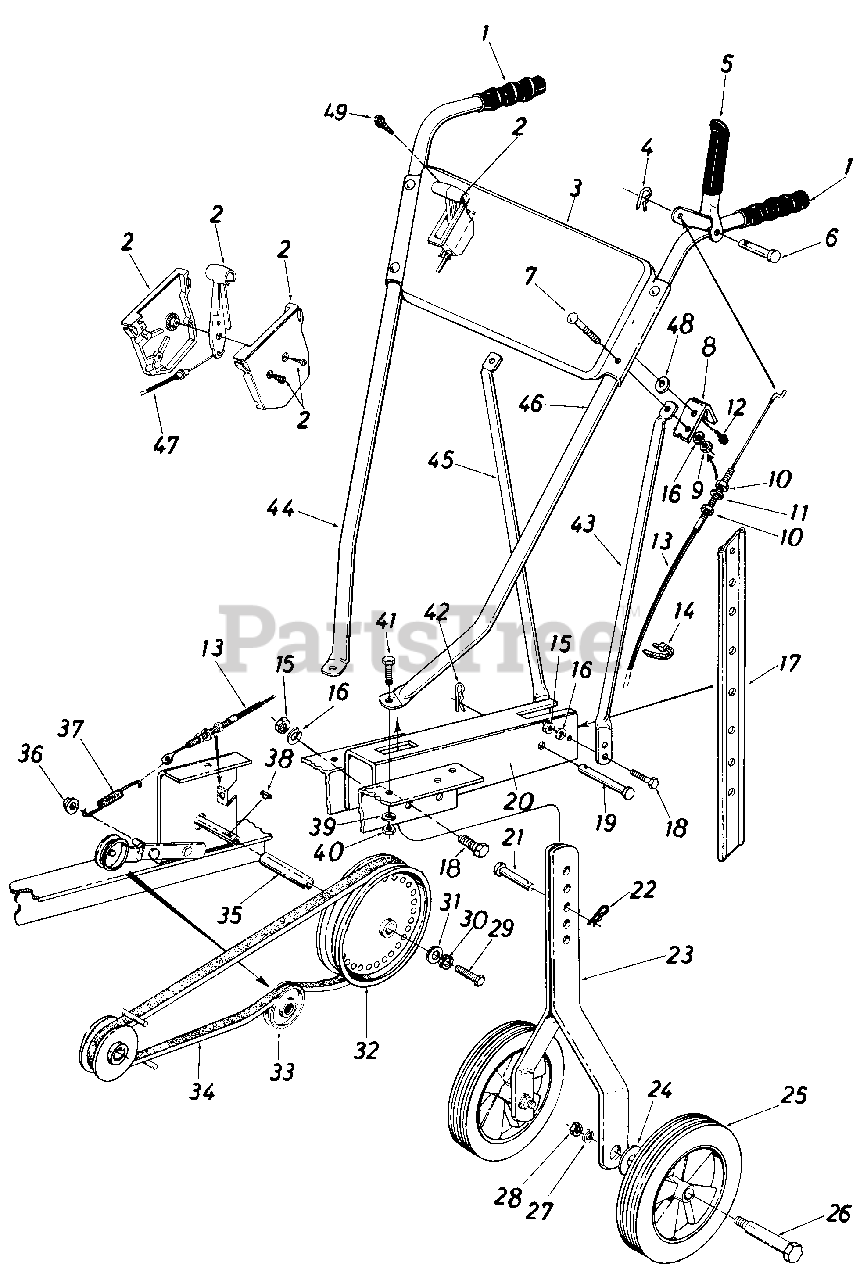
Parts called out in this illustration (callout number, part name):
2	Throttle Control Box
3	Handle Panel
4	Int. Cotter Pin
5	Clutch Grip Ass'y.
7	Carriage Bolt 5/16-18 x 1.75"-Lg.*
8	Cable Support Brkt.
9	Hex Nut 5/16-18 Thd.*
10	Hex Jam Nut 5/16-24 Thd.
11	L-Wash. 5/16" I.D.*
12	Hex Wash. Hd. Self-Tap Scr. 1/4-20 x .50" Lg.
13	Clutch Control Cable
15	Hex Nut 5/16-18 Thd.
16	L-Wash. 5/16" I.D.
18	Hex Bolt 5/16-18 x .75" Lg.
19	Clevis Pin 1/2" Dia. x 2.50"-Lg.
20	Tailpiece Ass'y.
21	Clevis Pin 3/8" Dia. x 2.50" Lg.
22	Hairpin Cotter
23	Wheel Bracket Ass'y.
24	Belleville Wash. 1/2" I.D.
25	Wheel Ass'y. 9 x 1.75
26	Shoulder Bolt
27	L-Wash. 1/2" I.D.
28	Hex Nut 1/2-20 Thd.*
29	Hex Bolt 1/4-28 x .75" Lg.
30	L-Wash. 1/4" I.D.*
31	Fl-Wash. .25" I.D. x .930" O.D.
32	Pulley 6.00" O.D.
33	Idler Pulley
34	"V"-Belt 1/2" Pitch x 39" Lg.
36	Cap Speed Nut
37	Extension Spring
38	Hi-Pro Key
39	L-Wash. 5/16" I.D.*
40	Hex Nut 5/16-18 Thd.*
41	Hex Bolt 5/16-18 x .75" Lg.
42	Hairpin Cotter
43	Handle Support Bracket-L.H.
44	Handle Bar-R.H.
45	Handle Support Bracket-R.H.
46	Handle Bar-L.H.
47	Throttle Control Cable-35"
48	Fl-Wash. .281" I.D. x .50" O.D.
49	Self-Tap Scr. #10 x 1/2" Lg.
